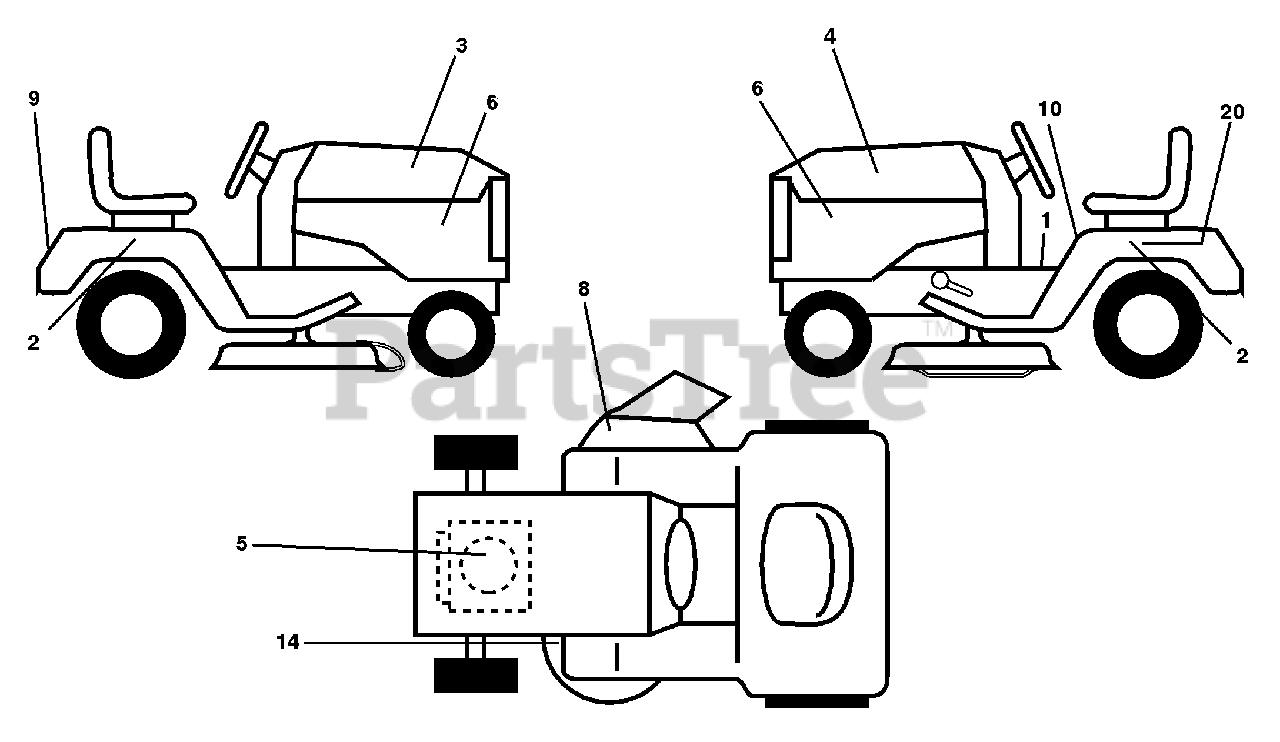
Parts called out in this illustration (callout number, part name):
1	Decal Oper. Step Thru Eng/Fr
2	Decal Fender Auto Husq Radius
3	Decal Hood RH
4	Decal Hood LH
5	Decal HP Engine
6	Decal Pnl Side
8	Decal Warning
9	Decal Fender Husq
10	Decal Fender Danger Eng/Fr
14	Decal V-Belt Schematic
20	Decal Bat Dan/Psn
MK380	Mulcher Kit with Blades
